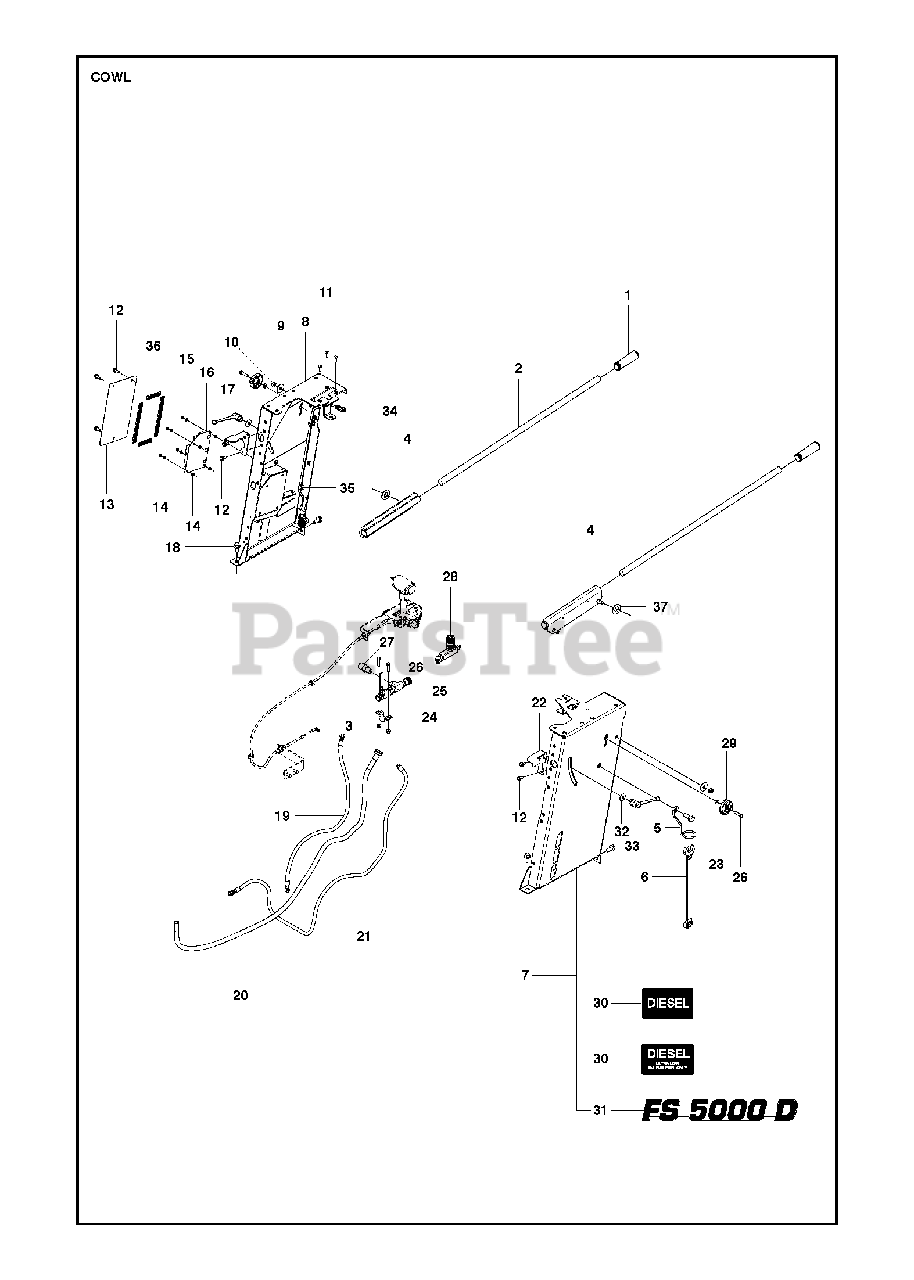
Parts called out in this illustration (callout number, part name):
9	WASHER
11	SCREW IHCSFM
23	HEXAGON NUT FLANGE
29	TURNING KNOB
37	WASHER, FRICTION 1/2 X 1" OD
